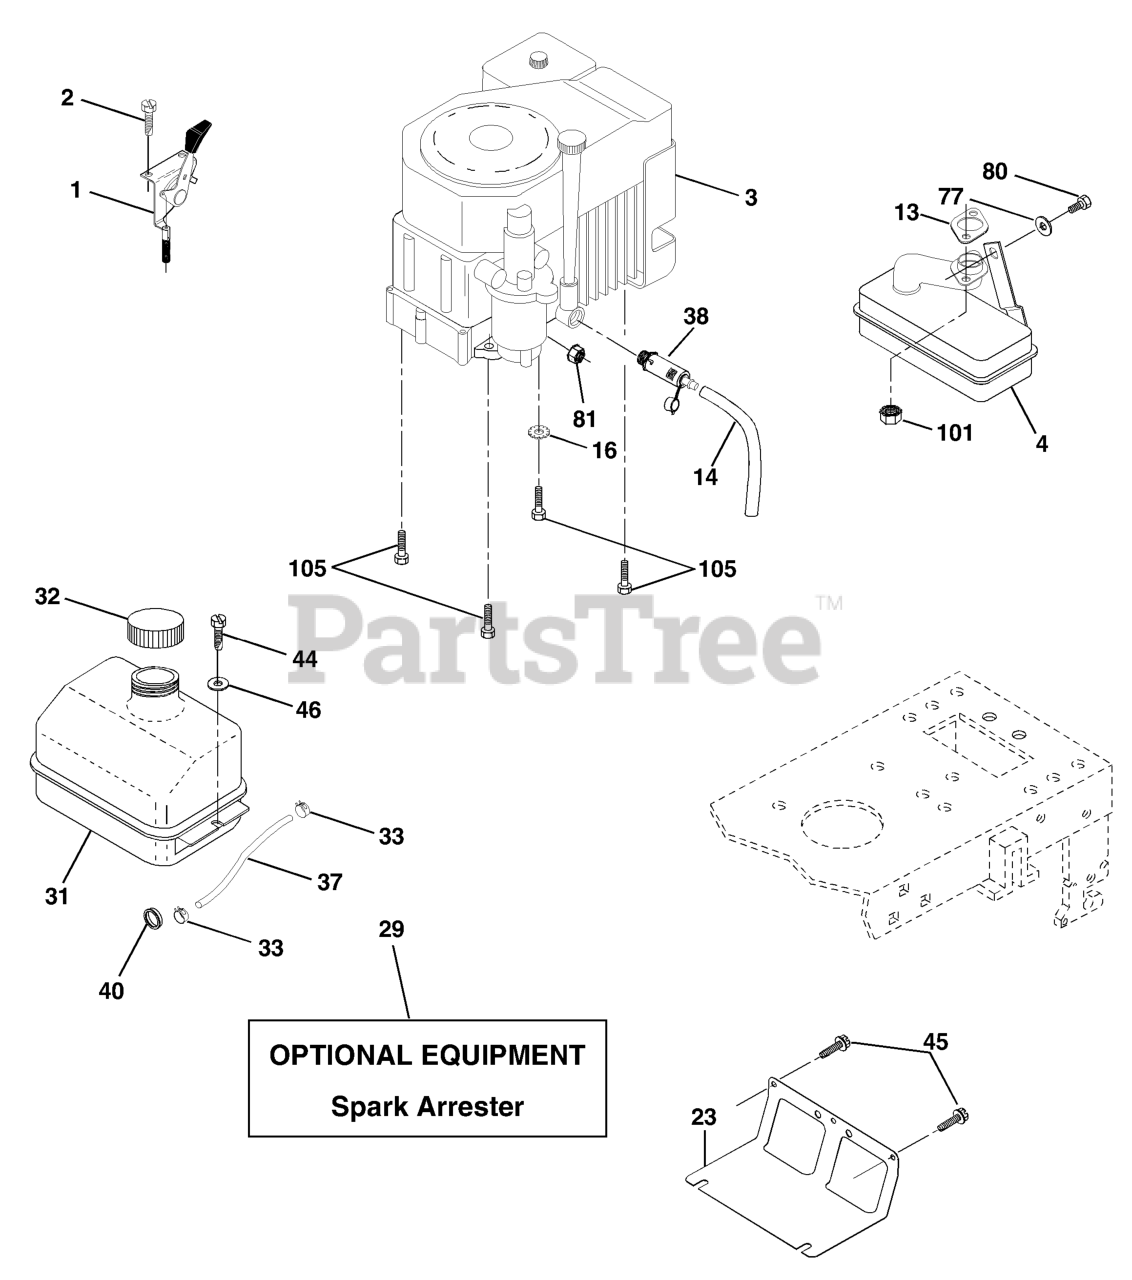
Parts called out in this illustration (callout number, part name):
1	CONTROL.THROTTLE.LT/YT
2	SCREW
4	MUFFLER.KOHL.CV.SINGLE.W/PORT
13	KOHLER GASKET
14	TUBE, DRAIN OIL ASM.
16	LOCKWASHER
23	SHIELD.BROWNING.DBR.GUARD
29	KIT.SPARK ARRESTOR 794945 B&S
31	TANK FUEL LT
32	FUEL CAP
33	HOSE CLAMP
37	LINE.FUEL.20
38	PLUG, OIL DRAIN EASY
40	BUSHING.SNAP.NYL.BLK.
44	SCREW HEXWSHR 1/4-20X3/4
45	SCREW, 3/8-16X3/4
46	WASHER
77	WASHER
80	Bolt Hex Hd 5/16-18 x 1/2
81	NUT
101	FLANGE NUT
105	SCREW 3/8-16X1
